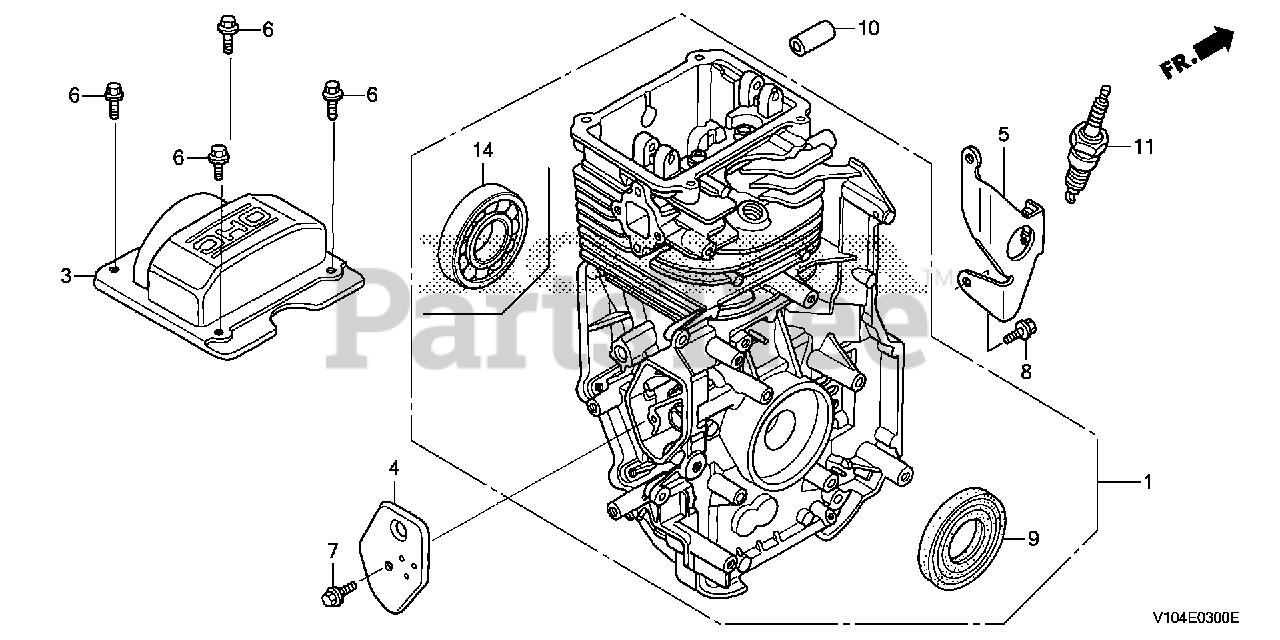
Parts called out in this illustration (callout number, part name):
1	CYLINDER ASSY.
3	COVER, CYLINDER HEAD
4	COVER, BREATHER (BREATHER VALVE ASSY.)
6	BOLT, FLANGE (6X12) (CT200)
7	BOLT, FLANGE (6X14) (CT200)
9	OIL SEAL (25.4X62X6)
11	SPARK PLUG (BPR5ES) (NGK)
